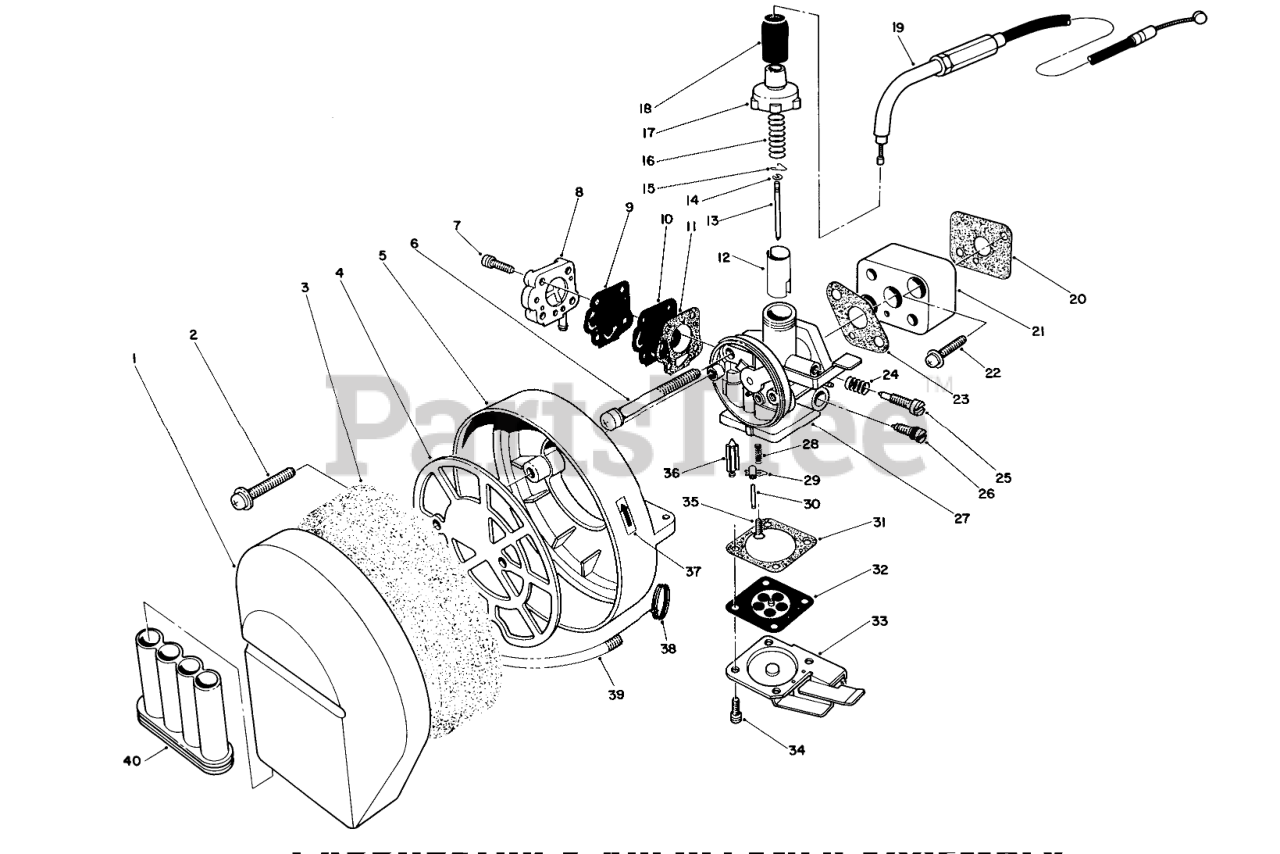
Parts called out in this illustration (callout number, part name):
1	CLEANER COVER
2	SCREW & WASHER
3	CLEANER ELEMENT
5	CLEANER CASE
6	SCREW & WASHER
7	Screw
8	PUMP COVER ASM
9	PUMP DIAPHRAGM
10	PUMP CHECK VALVE
11	PUMP COVER GASKET
12	THROTTLE VALVE
13	Needle-Jet
14	SPRING RETAINER
15	Clip-Needle
16	Spring-Throttle
18	AIR SEAL
19	THROTTLE WIRE
20	GASKET
21	INSULATOR
22	SCREW & WASHER
23	CARBURETOR GASKET
24	SPRING
25	Screw-Adjusting
26	MAIN JET NEEDLE ASM
27	Carburetor Assembly (Incl. Ref. #7-18, 24-26, & 28-36)
28	SPRING
29	FLOAT ARM
30	FLOAT PIN
31	GASKET
32	MAIN DIAPHRAGM ASM
33	COVER
34	SCREW W/ WASHER
35	FLOAT SCREW
36	FLOAT VALVE
37	CHOKE LABEL
38	SPRING
39	SPRING
